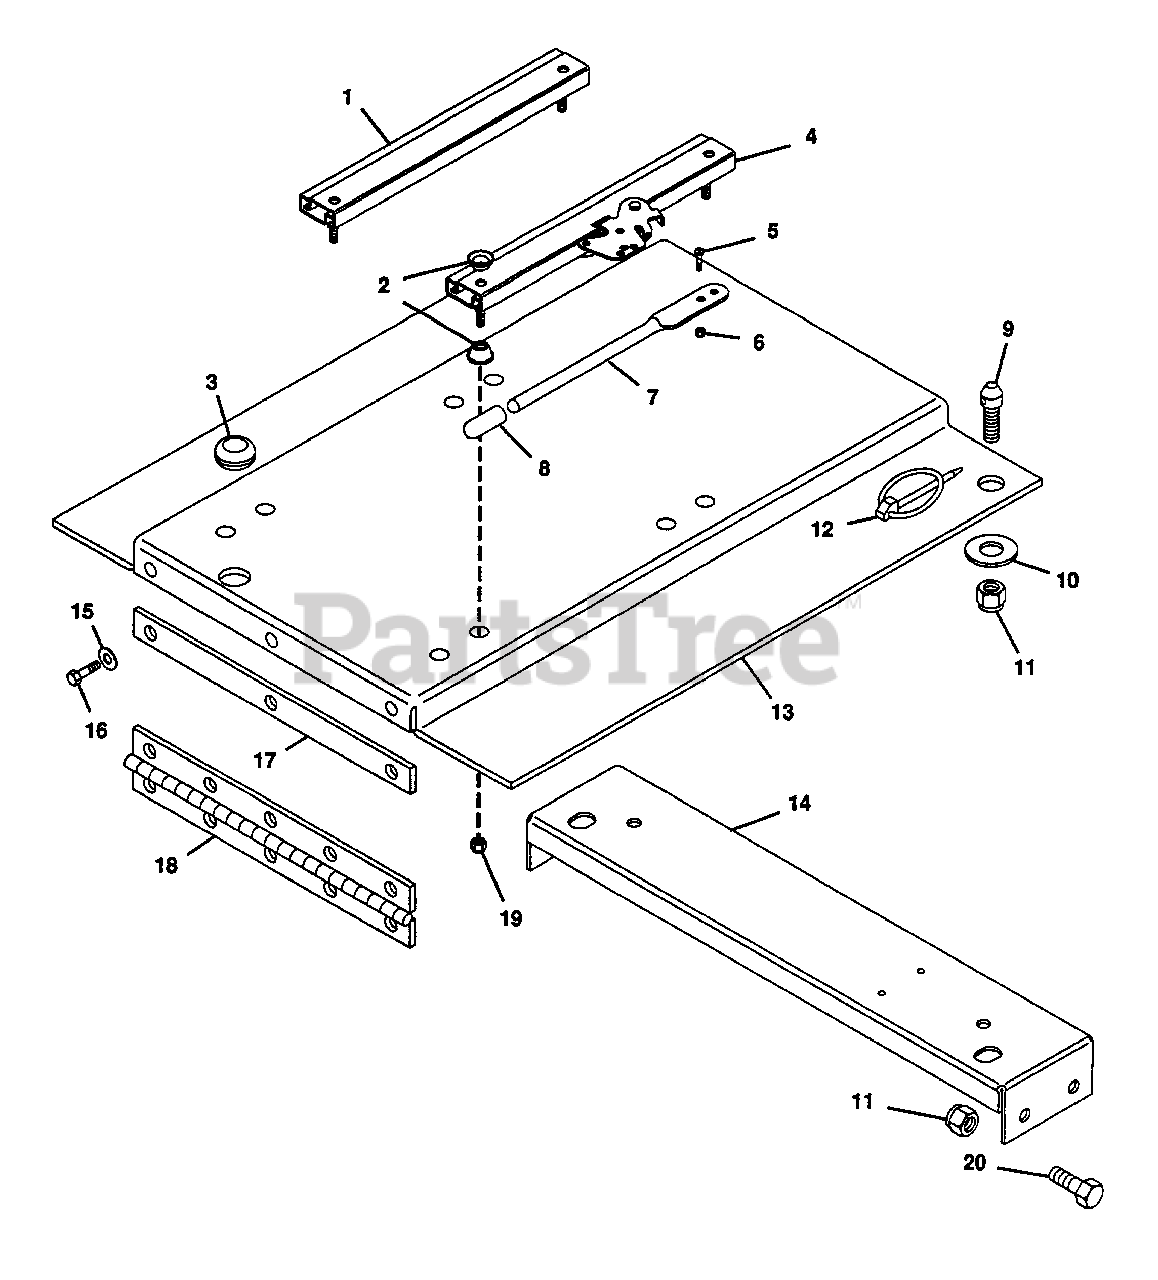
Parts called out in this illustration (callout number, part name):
1	Adjuster, Seat
2	Bush., Flg. .375x1.16x.320 Stl.
3	Grommet, .75
4	Adjuster, Seat w/Latch
5	Screw, Machine 10-24x.625 PHD
6	Nut, Lock 10-24
7	Handle, Seat Slide
8	Tips, Brake Lock Lever
9	Pin, Catch
10	Washer, Flat .531x1.062x.095
11	Nut, Lock 1/2-13
12	Pin, Klik
13	Plate, Deck
14	Bracket, Deck Plate
15	Washer, Flat .344x.688x.065
16	Bolt, Hex 5/16-18x.75
17	Plate, Clamping
18	Hinge
19	Nut, Lock 5/16-18
20	Bolt, Hex 1/2-13x1.00
